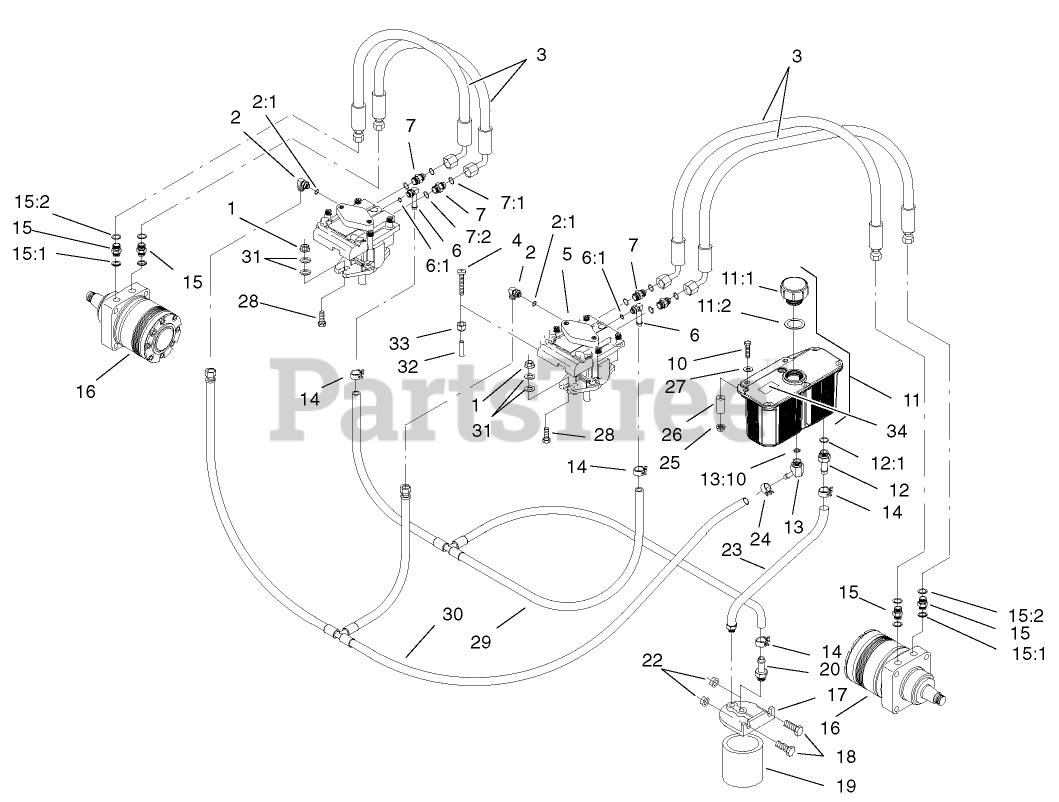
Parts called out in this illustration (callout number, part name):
1	NUT-HHF, WHIZ
2	FITTING-90 DEG
2:1	O-RING
3	HOSE-PRESSURE, HIGH
6	FITTING
6:1	O-RING
7	FITTING-STRAIGHT
7:1	O-RING
7:2	O-Ring
10	SCREW-HH
11	Reservoir-HYD
11:1	CAP-RESERVOIR, HYD
11:2	GASKET-CAP
12	ADAPTER-STRAIGHT
12:1	O-RING
13	Elbow-45deg.
13:10	O-Ring
14	Clamp-Hose
15	Fitting-Straight
15:1	O-RING
15:2	O-Ring
16	HYD MOTOR ASM
17	HEAD-FILTER
18	SCREW-HH
19	FILTER-OIL, HYD
20	Adapter-Straight
22	NUT-HF
23	HYD Hose ASM
24	Clamp-Hose
25	NUT-HF
26	Spacer
27	WASHER-FLAT
28	SCREW-HH
29	HYD Hose ASM
30	HYD Hose ASM
31	WASHER-FLAT
32	GRIP-VALVE, DUMP
33	NUT-LOCK, NI
34	DECAL-TANK, HYD
